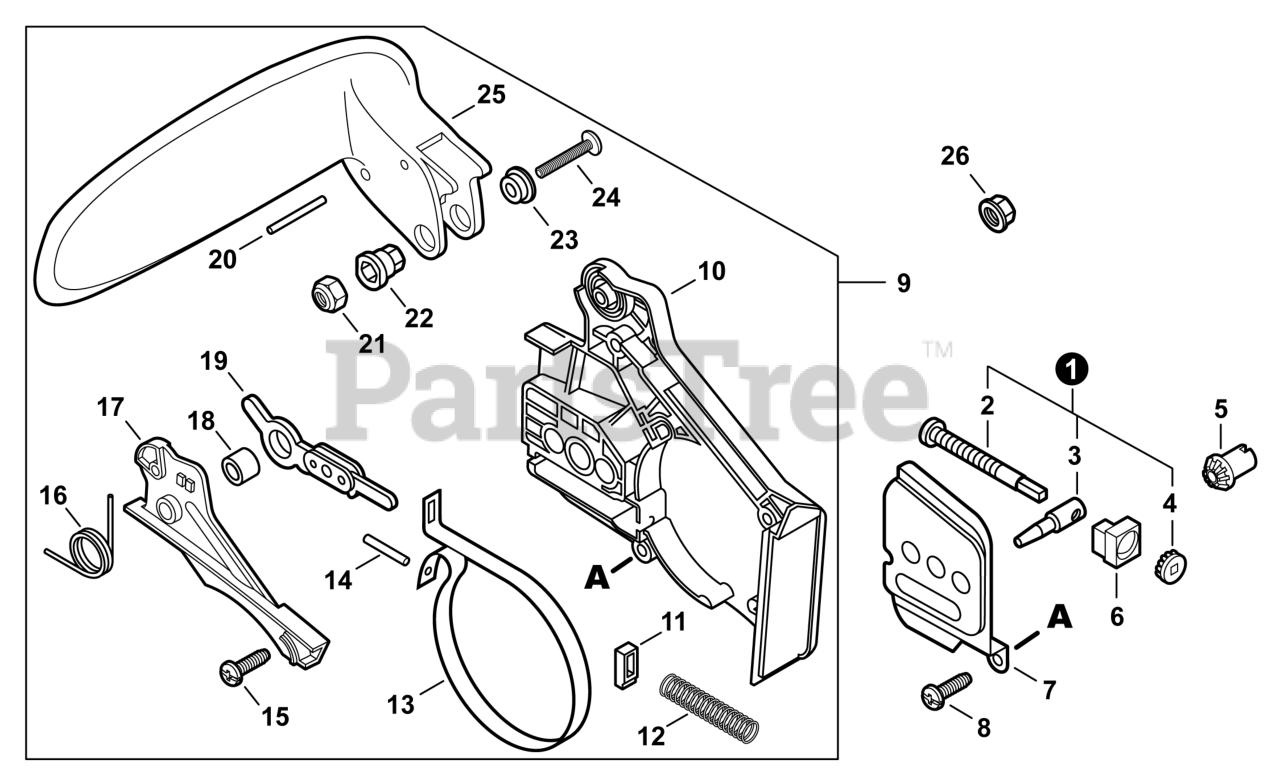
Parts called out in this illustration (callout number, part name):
1	TENSIONER SET, CHAIN
2	SCREW, CHAIN TENSION
3	TENSIONER, CHAIN
4	GEAR, BEVEL
5	GEAR, BEVEL
6	COLLAR 8
7	PLATE, GUIDE - OUTER
8	SCREW 4×10
9	BRAKE ASSY, CHAIN
10	GUARD, SPROCKET
12	SPRING, COMPRESSION
13	BAND, BRAKE
14	PIN, SPRING 3×9.8
15	SCREW 4×12
16	SPRING, TORSION
17	COVER, BRAKE
18	SPACER 8×12×9
19	CONNECTOR, BRAKE
20	PIN 3×26
21	NUT, LOCK M5
22	COLLAR 5
23	COLLAR 5.3×10×13×L5
24	SCREW 5×32
25	BRAKE, CHAIN
26	NUT, FLANGE M8×1.25
